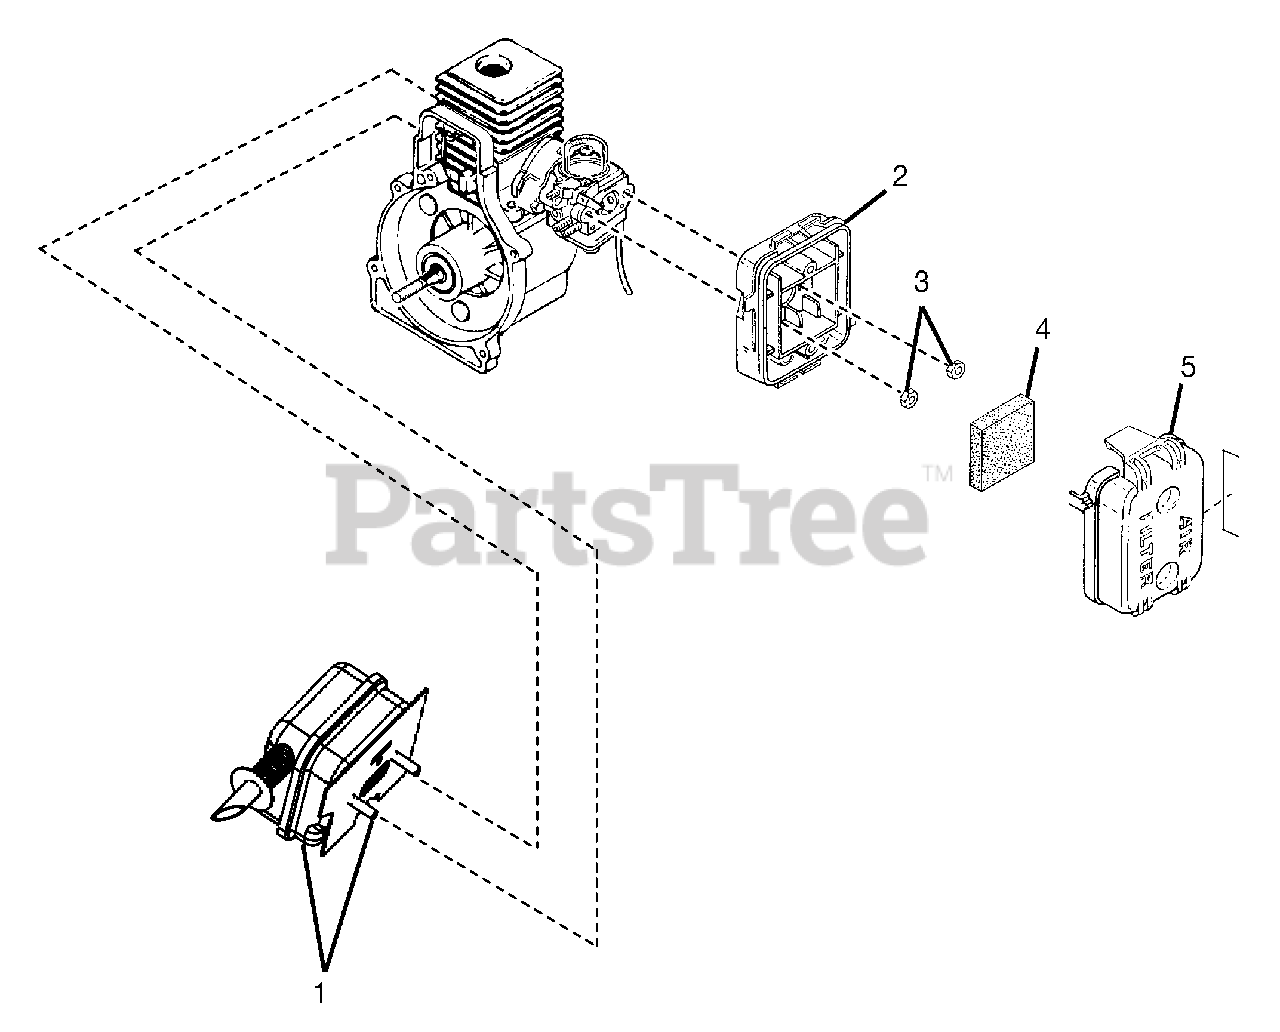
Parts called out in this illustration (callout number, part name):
1	MUFFLER COMPLETE
2	AIR FILTER BOX
3	HEX NUT (10-24)
4	AIR FILTER
5	AIR FILTER COVER
6	CHOKE DECAL
